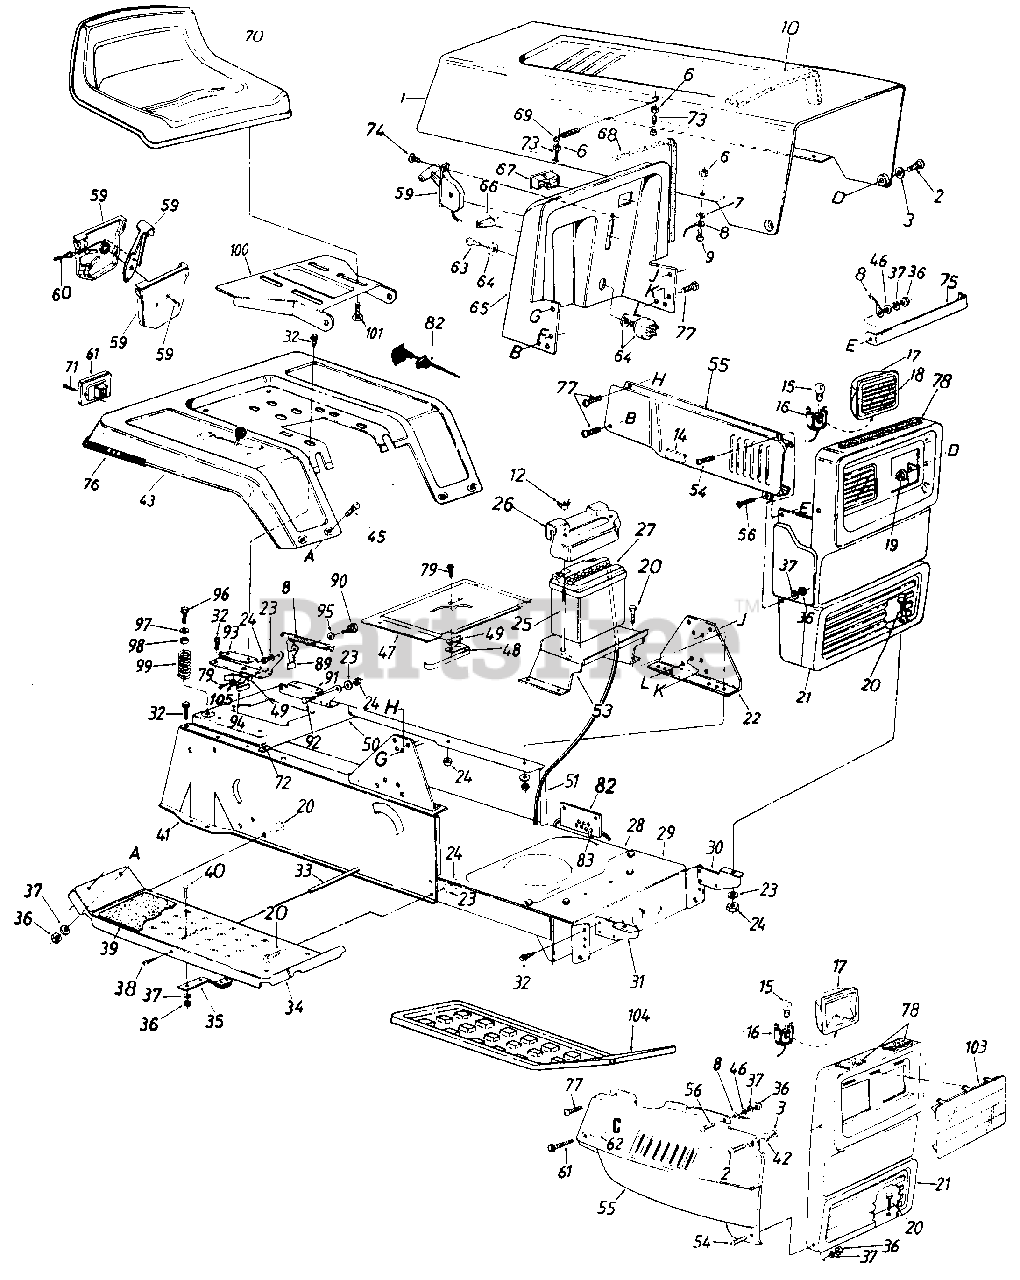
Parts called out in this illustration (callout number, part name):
1	Hood
2	Shld. Bolt .375 Dia. x .125
3	Washer .39" I.D. x .62" O.D.
6	Hex Sems Nut #10-24 Thd.
7	Fl-Wash. .203" I.D. x .41 O.D. x .040
8	Hood Stop
9	Truss Hd. Scr. #10-24 x 1/z" Lg.*
10	PVC Foam
12	Wing Nut 1/4-20 Thd.-Plastic
14	Rubber Strip
15	Lamp
16	Twist Lock-Lamp Socket
17	Headlight Housing
18	Lens
19	L-Nut 1/4-28 Thd.
20	Hex Bolt 5/16-18 x .75" Lg.
21	Grille
23	L-Wash. 5/16" I.D.
24	Hex Nut 5/16-18 Thd.
25	Battery Hold Down Rod
26	Battery Cover
27	12 Volt Battery
28	Lower Frame
29	Front Pivot Brk't.
30	Grille Mount Brk't.-L.H.
33	Running Board Rod
34	Running Board
36	Hex Nut 1/4-20 Thd.
37	L-Wash. 1/4" I.D.*
38	Truss Mach. Scr. 5/16-18 x .75" Lg.
39	Foot Pad
41	R.H. Side Frame
42	Shld. Spacer
43	Rear Fender
45	Carriage Bolt 1/4-20 x .50" Lg.*
46	Fl-Wash. .281" I.D. x .73" 0. D.
47	Transmission Panel
48	Reverse Safety Switch
49	Insulator Nut Plate
50	Hitch Plate
51	L.H. Side Frame
53	Battery Bracket
54	Truss Hd. Scr. 1/4-20 x .75" Lg.
56	Truss Mach. Scr. 1/4-20 x .50" Lg.
59	Throttle Control Box Ass'y.
60	Throttle Control Wire 35"
61	Hex TT-Tap Scr. 1/4-20 x 1.75" Lg.
62	Spacer 1.32" Lg.
63	Ignition Key
64	Ignition Switch
67	Ammeter
68	Trim Strip-27"
69	Hood Spring
70	Seat Ass'y.
72	Speed Nut #10Z
73	Hex Scr. #10-24 x 1.0" Lg.
74	Truss Mach. AB-Tap Scr. #10 x .5" Lg.
75	Tie Strap-Grille/Side Panelt
76	Trim Strip-81"
77	Hex Wash. Hd. Tap Scr. 1/4 x .75" Lg.
78	Foam Strip 3/8 x 1-1/8 x 1-1/2" Lg.
79	Hex Wash. Hd. AB-Tap Scr. #8 x .50" Lg.
82	Brake Cable Bracket
83	Cable Tie
90	Shld. Bolt .437" Dia. x .268"
91	Seat Pivot Brkt. Support-L.H.
92	Shld. Bolt .437" Dia. x .162"
93	Seat Pivot Brkt. Support-R.H.
94	Spring Switch
95	Spr.-Wash..445" I.D.,
96	Hex Wash. Hd. Tap Scr. 5/16-1 8 x 1 " Lg.
97	Fl-Wash. .344" I.D.
98	Bushing
99	Compression Spring
100	Seat Pivot Bracket
101	Hex Tap Scr. 3/8-16 x .75" Lg.
103	Headlight Bezel
104	Foot Pad-L.H
105	Fiber Washer
